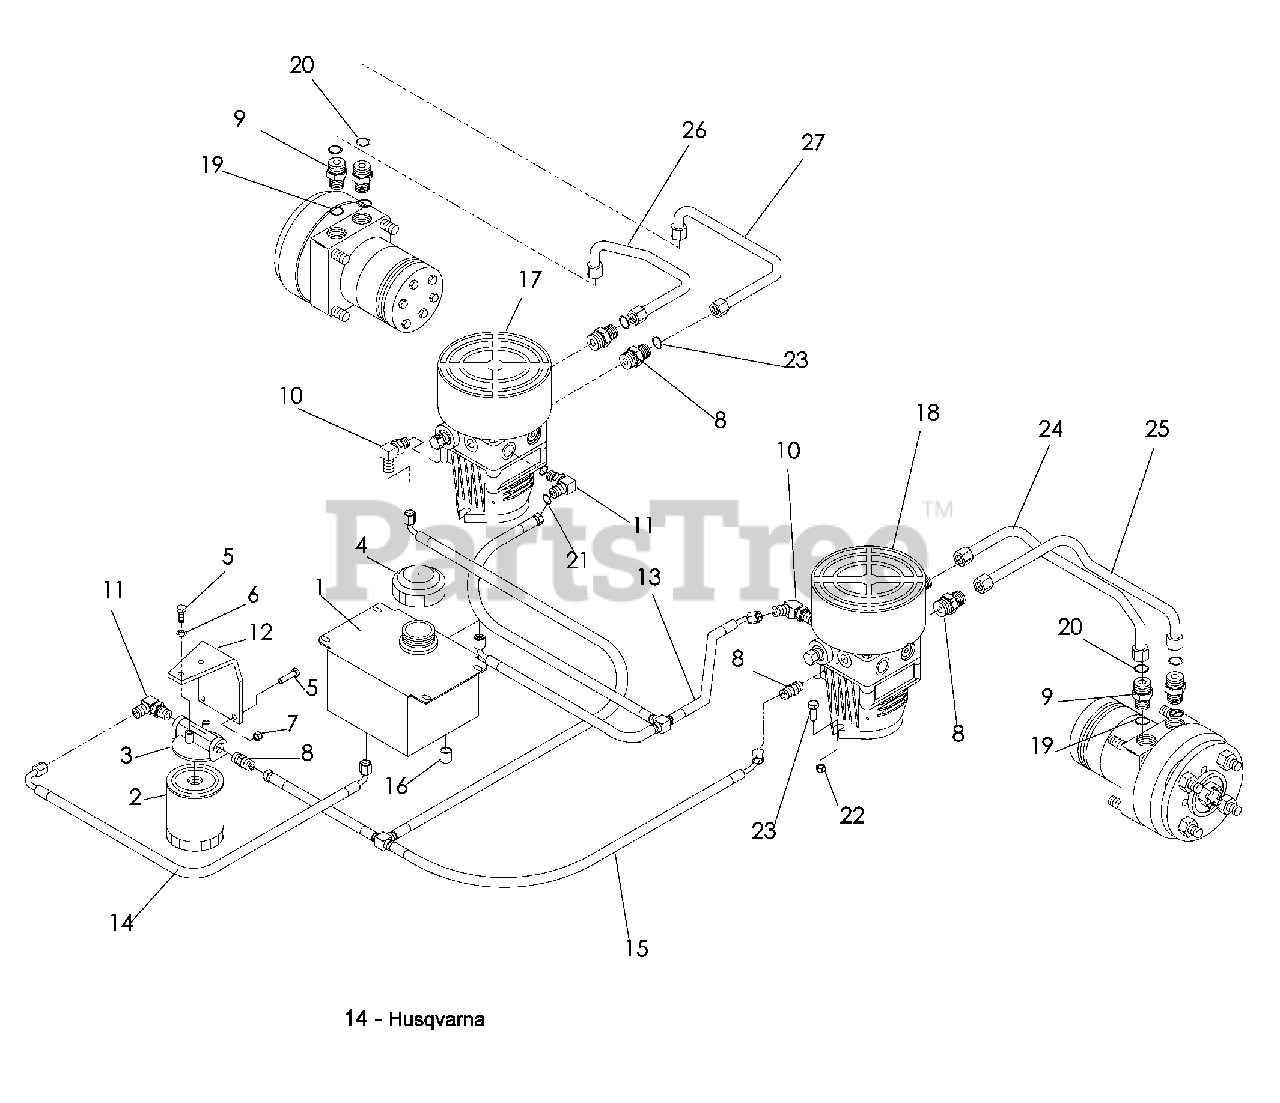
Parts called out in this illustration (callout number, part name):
3	FILTER HEAD
4	CAP, HYDRAULIC
5	HCS ¼- 20 x ¾
6	LOCKWASHER ¼
7	NUT ¼-20 HEX NYLOC
8	HYDRAULIC FITTING
9	STRAIGHT FITTING
12	BRACKET, FILTER
13	T’ ASSEMBLY, RETURN
14	HOSE
15	T’ ASSEMBLY, SUPPLY
17	PUMP W/FANS, 10CC, RT
18	PUMP W/FANS, 10CC, LT
22	NUT 3/8-16 CENTERLOCK
23	HCS 3/8-16 x 1 WHIZLK
24	HYDRAULIC LINE
25	HYDRAULIC LINE
26	HYDRAULIC LINE
27	HYDRAULIC LINE
